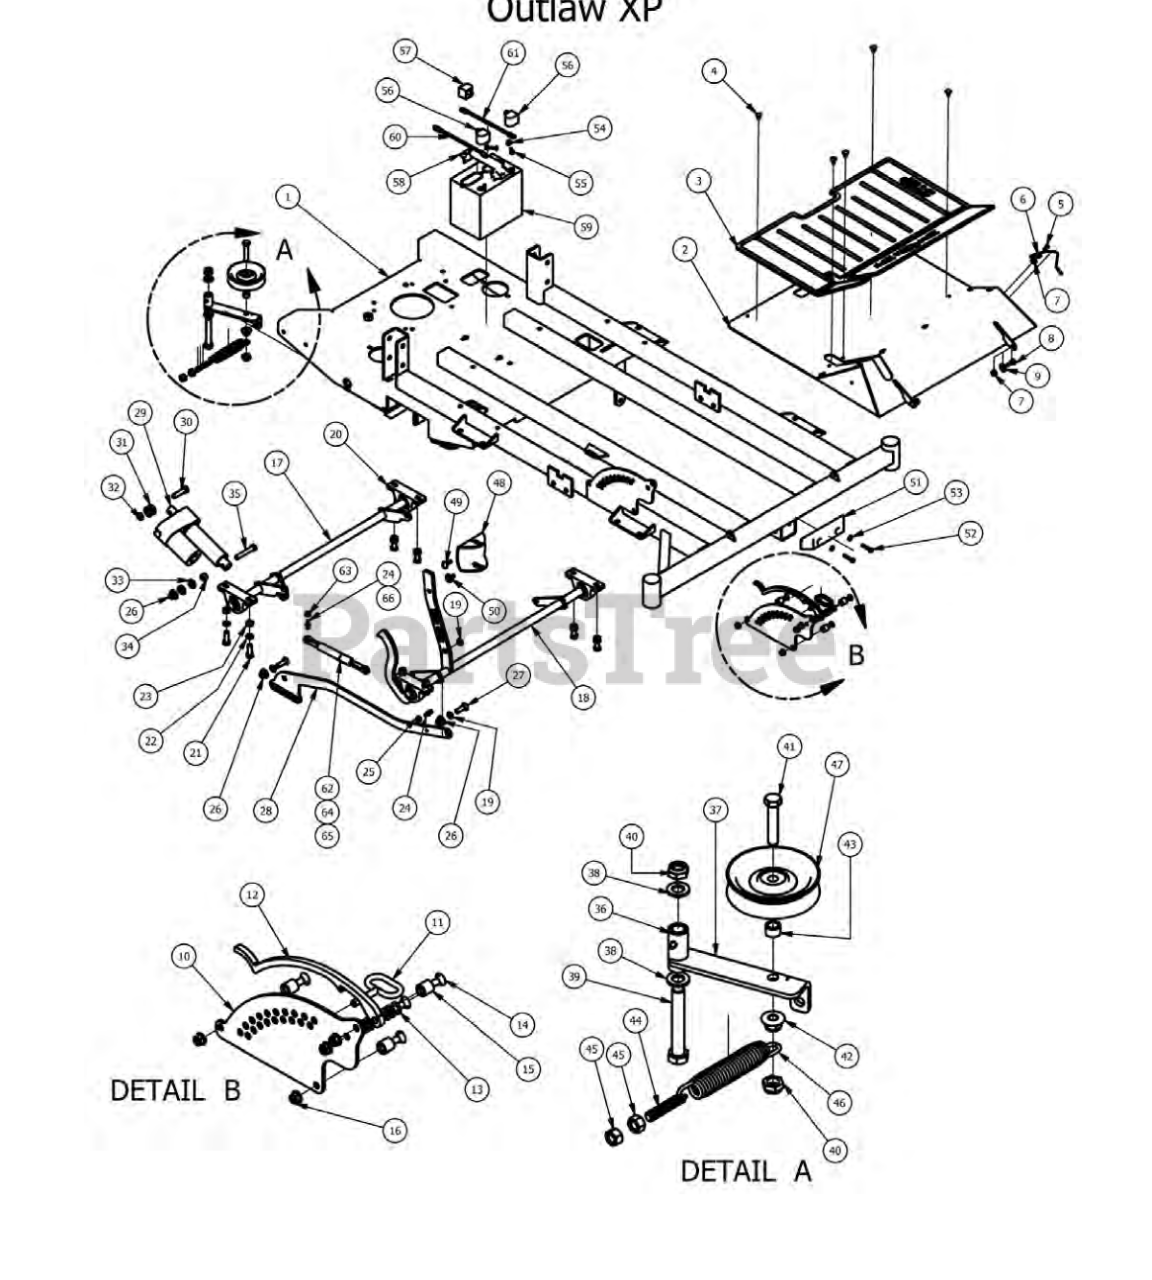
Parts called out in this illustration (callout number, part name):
1	Outlaw XP Frame
2	Outlaw Floor Panel
3	Foot Assist Floor Mat
4	Ratchet Fastener
5	1/4" x 5/8" BS C/S 18-8 SS
6	Floor board Cable W/ Swivel Ends
7	5/16-18 Nylon Flange Nut
8	5/16" x 1" Carriage Bolt
9	360 ID Plastic Washer
10	Outlaw Height Indicator Plate (Outer)
11	Deck height lever pin
12	Outlaw Deck Lever Lock
13	,390x.750 x 062 Nylon Washer
14	3/8 x 13/4 Carriage Bolt
15	3/4 OD x 1/2 ID x 3/4 Length
16	3/8" Nylock Flange Nut
17	Outlaw Actuator Bar (Rear)
18	3/4 OD x 1/2 ID x 3\4 Length
19	Bushing- SF-1620-4
20	pillow block 2bolt sealmaster
21	1/2 x 1 1/2" Hex Bolt
22	1/2 Lock Washer
23	1/2" Hex Nut
24	10mm Damper Ball Stud-Steering
25	5/16" Flange Nut
26	1/2-13 Nylon Flange Nut-Orange
27	1/2 x 1-1/2 Carriage Bolt
28	Outlaw Susp Frame Linkage Bar
30	1/2-13x2 GR 5 Hex Bolt
31	1/2" Washer (Grade 8)
32	1/2" Nylcock Nut (1/2 Jam)
33	.635 ID Plastic Washer
34	1/2 x 1/2 Spacer
35	1/2-13 x GR 5 Hex Bolt Zinc
36	Pump Idler assembly Componets 37,41,42,43,47
37	Pump Idler Bracket
38	.635 ID Plastic Washer
39	5/8" x 4" Hex Bolt
40	5/8" Nylock (1/2 Jam)
41	1/2-13 x 2 3/4 GR 5 Bolt
42	1/2-13 Nylon Flange Nut-Orange
43	1/2 x 1/2 Spacer
44	All Thread-pump Idler Tensioner
45	1/2" Hex Nut
46	Pump Idler Spring
47	43/4" Idler Pulley
48	Outlaw Deck Lift Pedal
49	5/16-18 x1 Thumb Screw Zinc
51	8" Rubber Bumper
52	1/4" x 1 1/2" Self Tapping Screw
53	1/4" Flat Washer
54	1/4-20 Hex Flange Nuts Zinc w/Serrations
55	1/4-20 x 3/4 GR 5 Hex Bolts Zinc
56	Black Boot For ground cable
58	Hold Down Assembly
60	Starter to chassis cable
61	Red battery cable
62	200 lb Gas Spring- 54" Deck outlaw
63	5/16" Flange Nut
64	300 lb Gas Spring 72" Deck Outlaw
65	250 lb Gas Spring 61" Deck outlaw
66	13mm Ball Stud for 72" Deck Only
